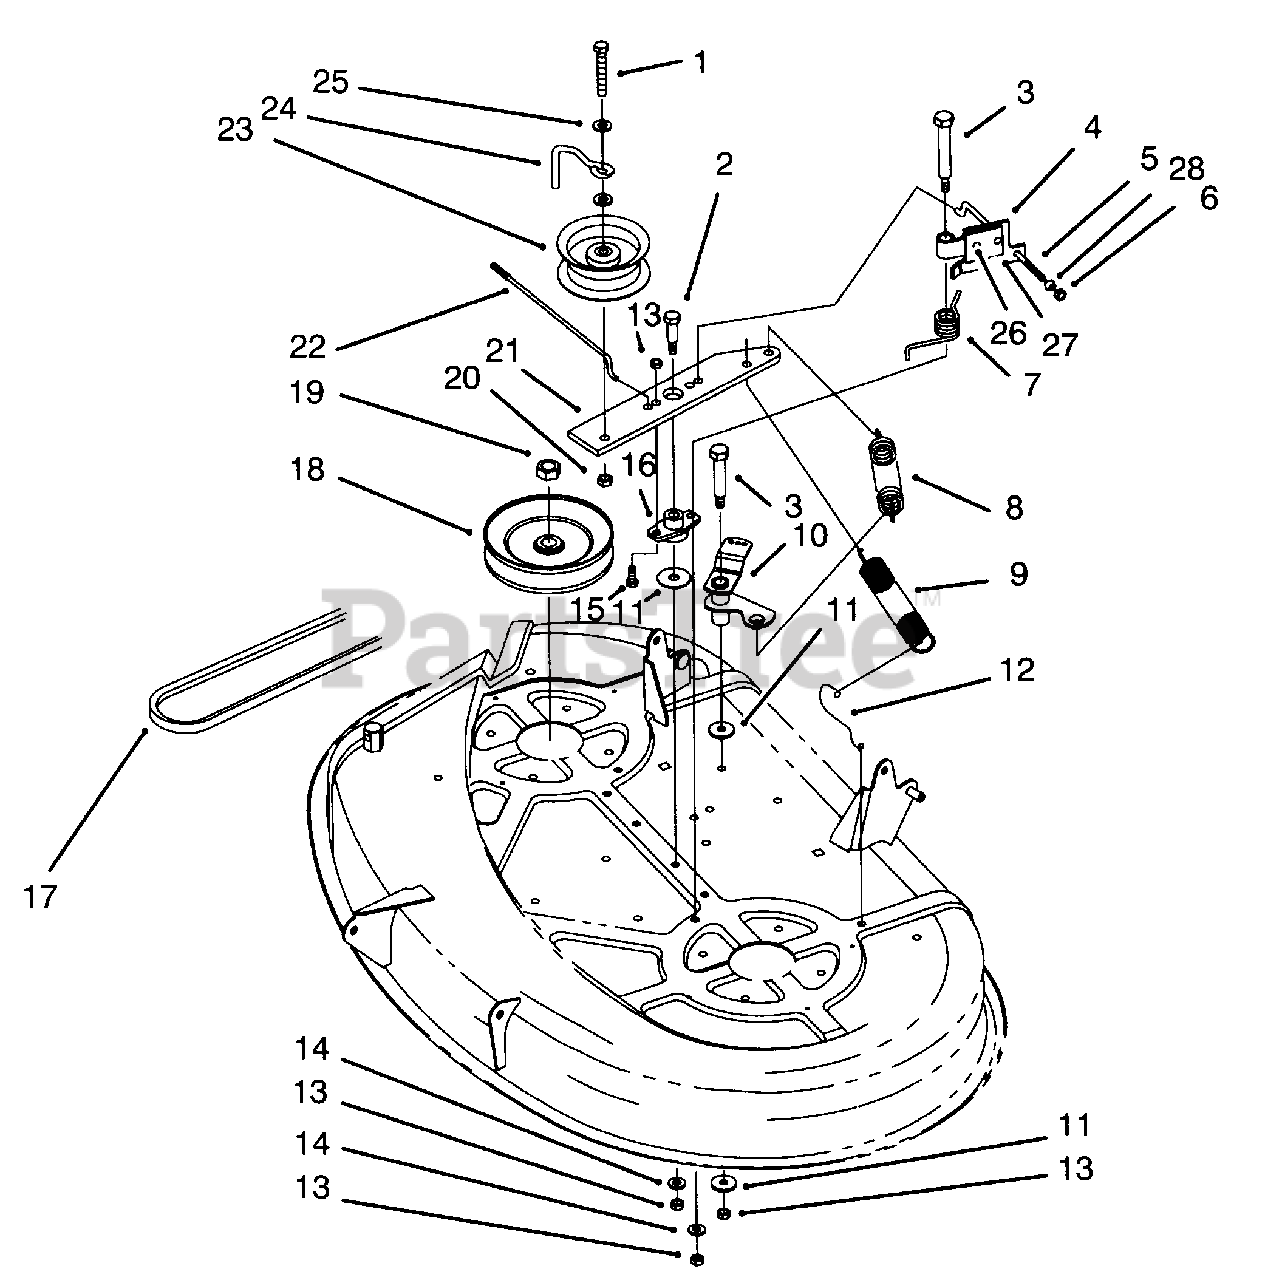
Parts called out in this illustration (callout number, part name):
1	Screw-Hex Hd. Cap
2	Bolt-Shoulder
3	Bolt-Shoulder
4	Brake-Deck (Incl. Ref. #26 & 27)
5	Rod-Deck Brake L.H.
6	Nut-Lock
7	Spring-Torsion
8	Spring-Deck Engage
9	Spring-Extension
10	Bellcrank
11	Washer-Fender
12	Hook-Spring Return
13	Nut-Lock
14	Washer-Flat
15	Screw-Hex Hd. Cap
16	Bushing-Idler Arm
17	V-Belt-Deck
18	Pulley-Deck
19	Nut-Lock
20	Nut-Lock
21	Arm-Idler
22	Rod-Deck Brake R.H.
23	Pulley-Idler
24	Guide-Idler Belt
25	Washer-Flat
26	Rivet-Pop
27	Pad-Brake
28	Ball-Swivel
